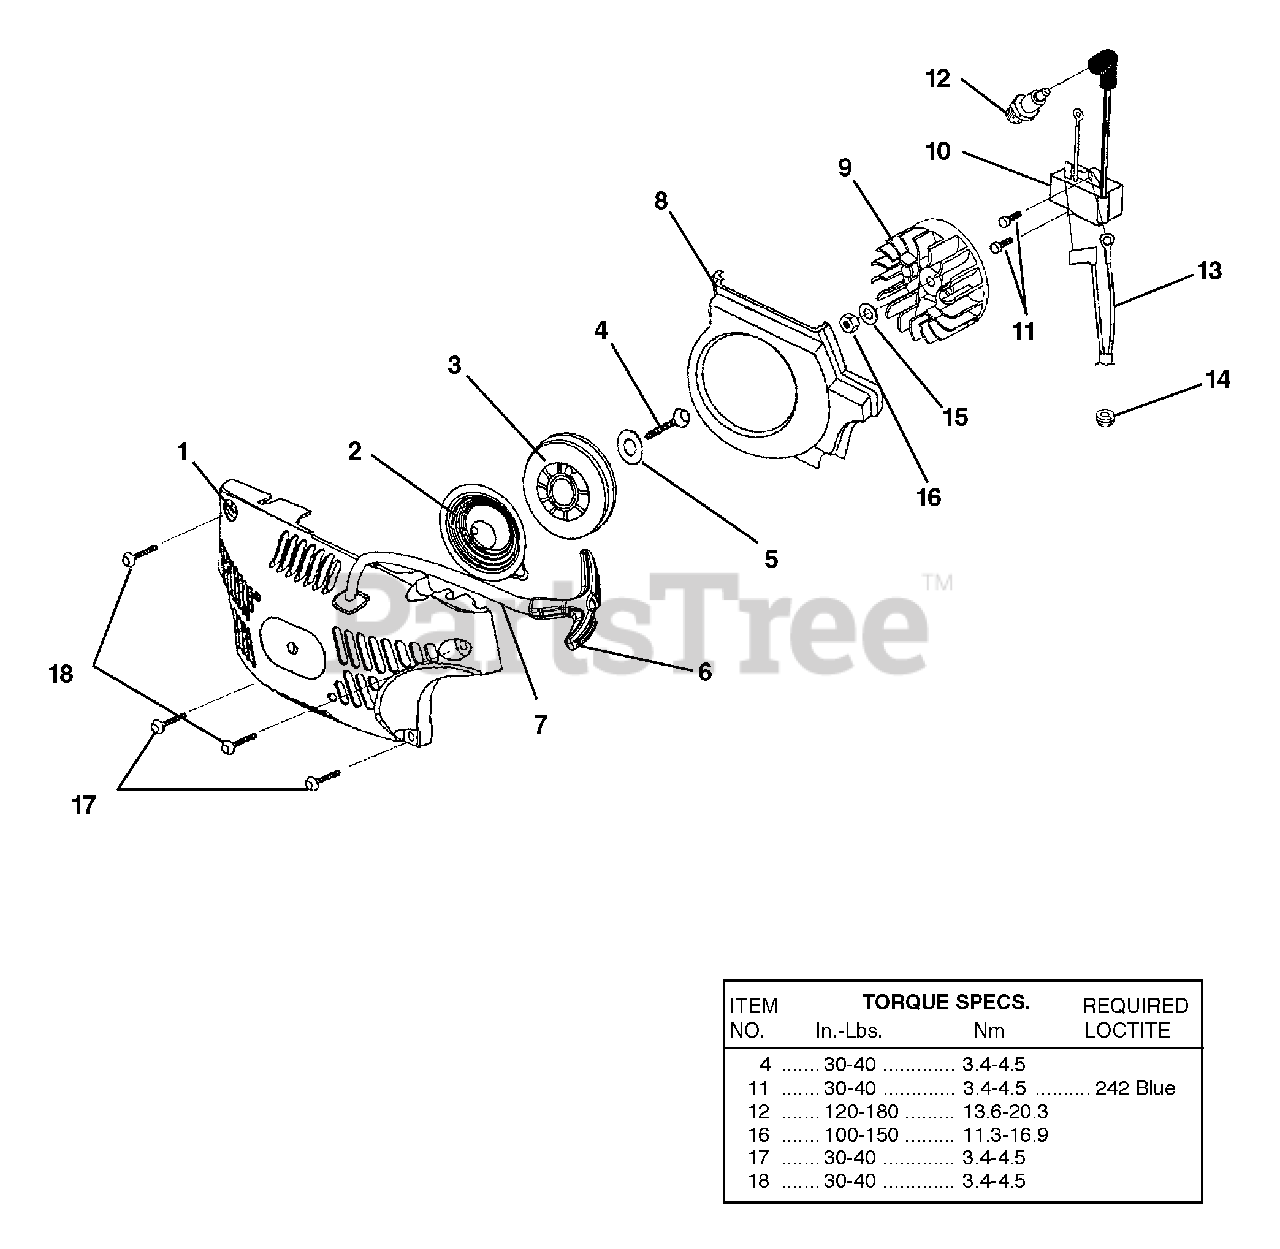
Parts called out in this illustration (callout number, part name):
1	Starter Kit
2	Spring & Container
3	Pulley, Starter
4	Screw, Thread Form, Plastite (10-14 x 5/8")
5	Washer, Retaining
6	Grip, Starter
7	Rope, Starter 46"
8	Baffle, Fan Housing
9	Rotor & Starter Pawl
10	Ignition Kit (33cc models)
11	Screw, Thread Form (8-32 x 5/8")
12	Spark Plug
13	Ignition Switch Harness
14	Grommet, Wire Harness (Split)
15	Washer, Flat
16	Nut, Jam
17	Screw, Truss Hd., Plastite (10-14 x 7/8")
18	Screw, Truss Hd., Plastite (10-14 x 5/8")
